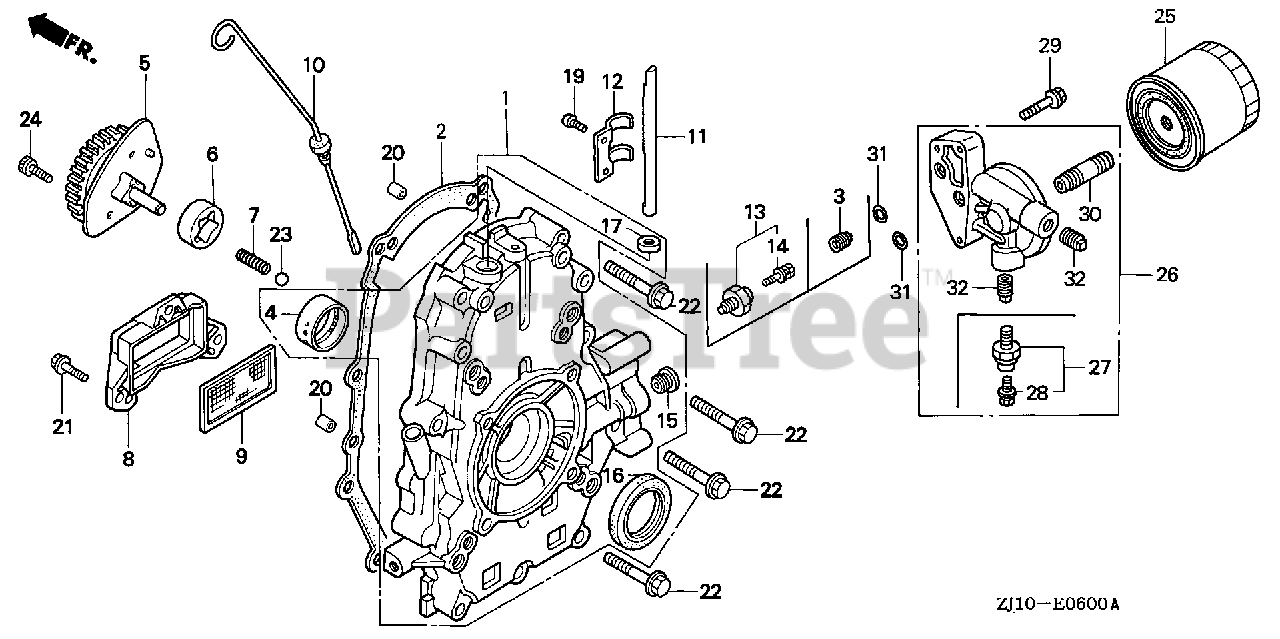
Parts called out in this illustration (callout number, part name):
1	COVER ASSY., CRANKCASE (MUFFLER)
2	GASKET, CASE COVER
3	BOLT, SEALING
4	BEARING A, MAIN (BLUE) (TO SELECT CORRECT BEARING, SEE THE SERVICE MANUAL.)
4	BEARING B, MAIN (BLACK) (TO SELECT CORRECT BEARING, SEE THE SERVICE MANUAL.)
4	BEARING C, MAIN (BROWN) (TO SELECT CORRECT BEARING, SEE THE SERVICE MANUAL.)
5	COVER ASSY., OIL PUMP (THREE BOLTS)
6	ROTOR, OIL PUMP (OUTER)
7	SPRING, RELIEF VALVE
8	COVER, OIL FILTER
9	SCREEN, OIL FILTER
10	DIPSTICK, OIL
11	SHAFT, GOVERNOR ARM (NOT AVAILABLE)
12	FORK, GOVERNOR
16	OIL SEAL (38X58X11)
17	OIL SEAL (10X16X4.5)
19	SCREW, PAN (5X10)
20	PIN, DOWEL (8X14)
21	BOLT, FLANGE (6X20)
22	BOLT, FLANGE (8X50)
23	BALL, STEEL (#12) (3/8)
24	BOLT, SOCKET (6X16)
25	FILTER, OIL (FILTECH TOYO ROKI) (SOLD INDIVIDUALLY)
25	FILTER, OIL (TOYO ROKI) (SOLD INDIVIDUALLY)
26	BASE, OIL FILTER (A)
29	BOLT, FLANGE (6X35) (CT200)
30	HOLDER, OIL FILTER
31	O-RING (11.8X2.4)
32	BOLT, SEALING
